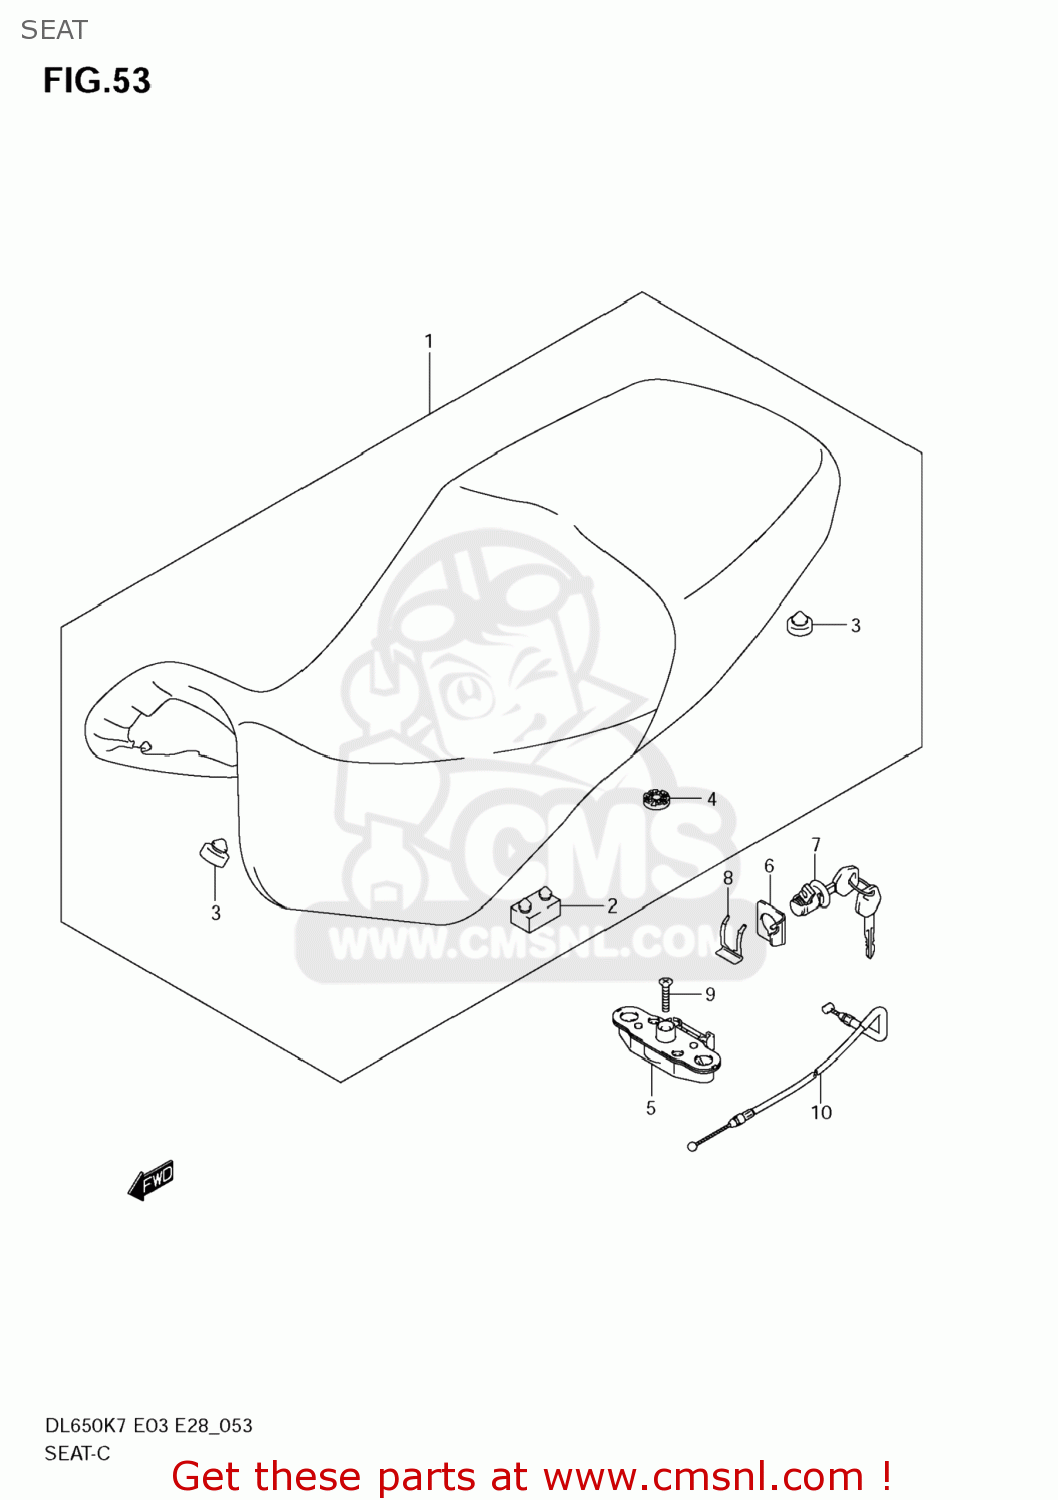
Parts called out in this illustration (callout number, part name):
1	SEAT ASSY
2	CUSHION,SEAT(40X20X15)
3	CUSHION
4	CUSHION,SEAT LOCK(10X22X6)
5	BRACKET,SEAT SUPPORT,RIGHT
6	GUIDE,SEAT LOCK CABLE
7	LOCK SET,SEAT
8	PLATE,SEAT LOCK ASSY
9	SCREW
10	CABLE,SEAT LOCK
